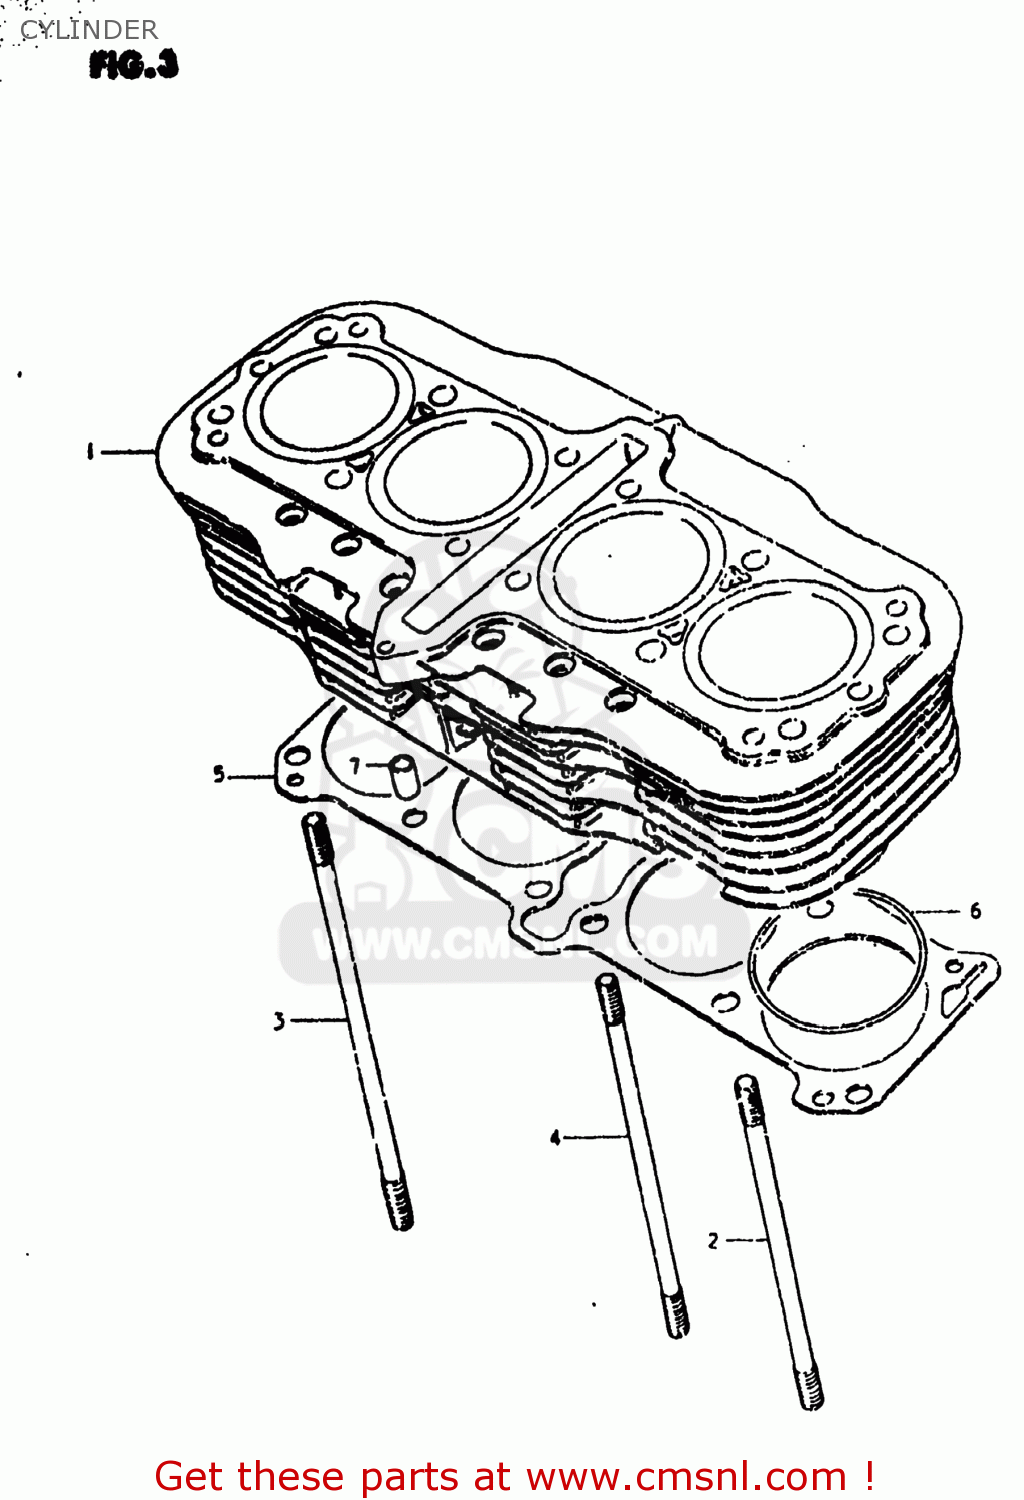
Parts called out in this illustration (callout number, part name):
1	CYLINDER
2	STUD
3	STUD
4	STUD
5	GASKET,CYLINDER (MCA)
6	O RING(D:2,ID:70)
7	PIN
